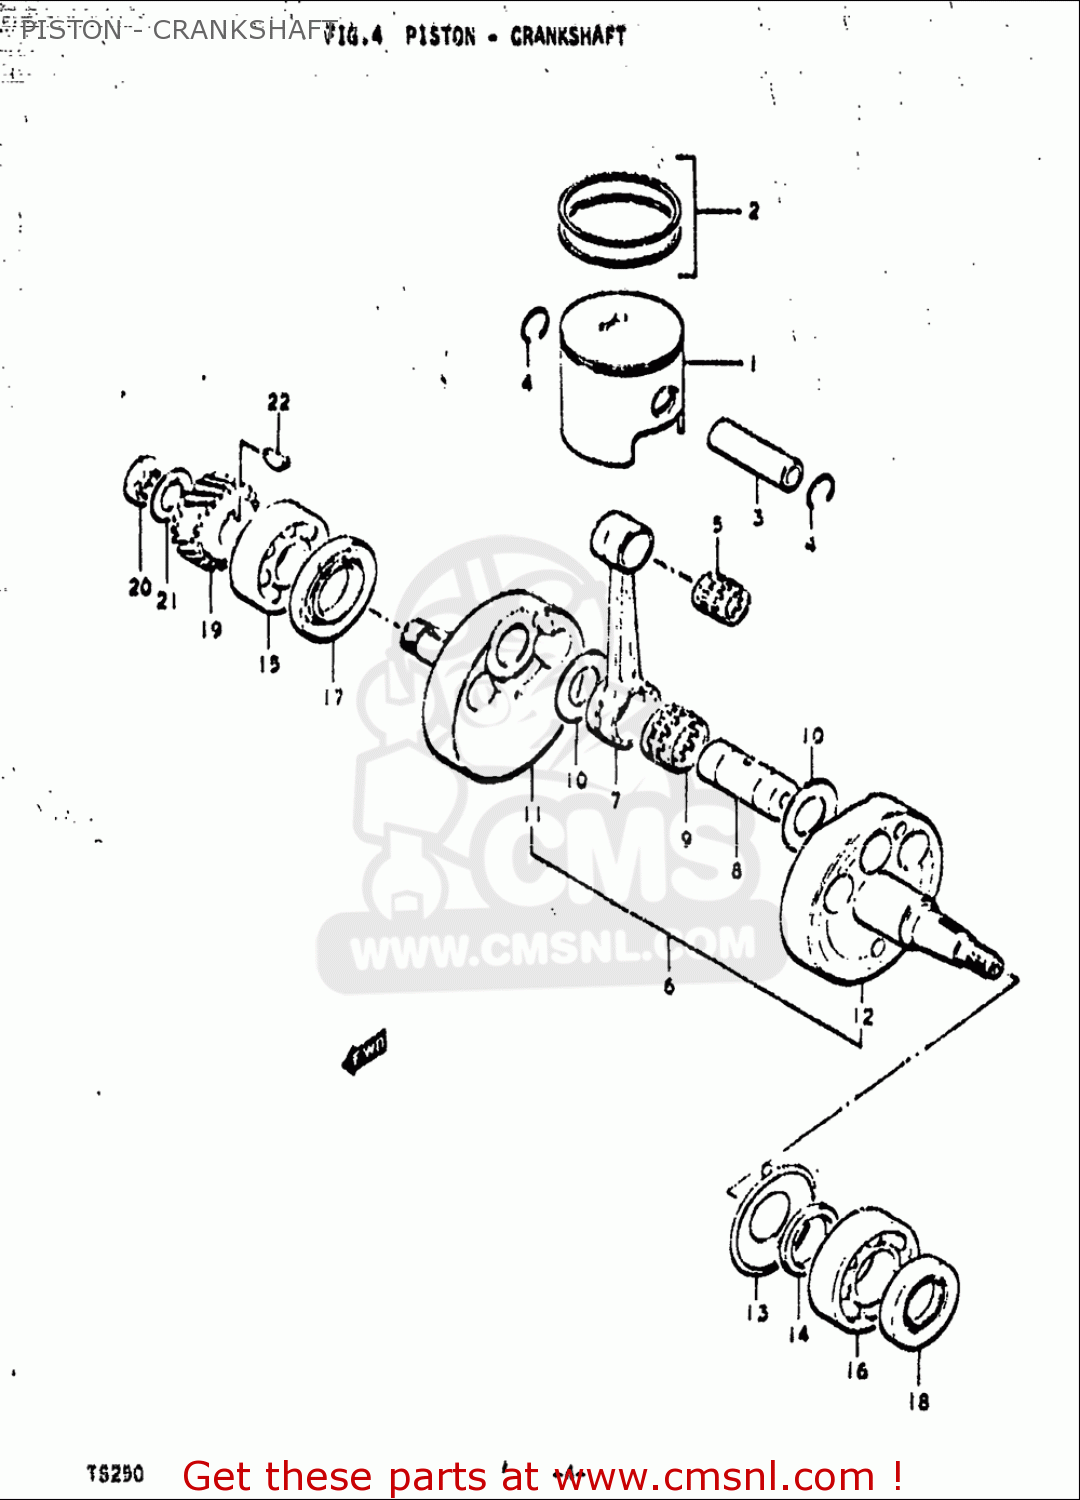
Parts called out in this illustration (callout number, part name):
1	PISTON
2	RING SET,PISTON
3	PIN,PISTON (18MM)
4	CIRCLIP,PISTON PIN
5	BEARING(18X23X24)
7	ROD,CONNECTING
8	PIN,CRANK
9	BEARING(25X31X20)
10	WASHER(25X40X1)
15	BEARING(25X62X17)
16	ROLLER BEARING (30X72X3
17	SEAL,OIL(35X62X9)
18	OIL SEAL (30X55X10)
20	NUT
21	WASHER
22	KEY
